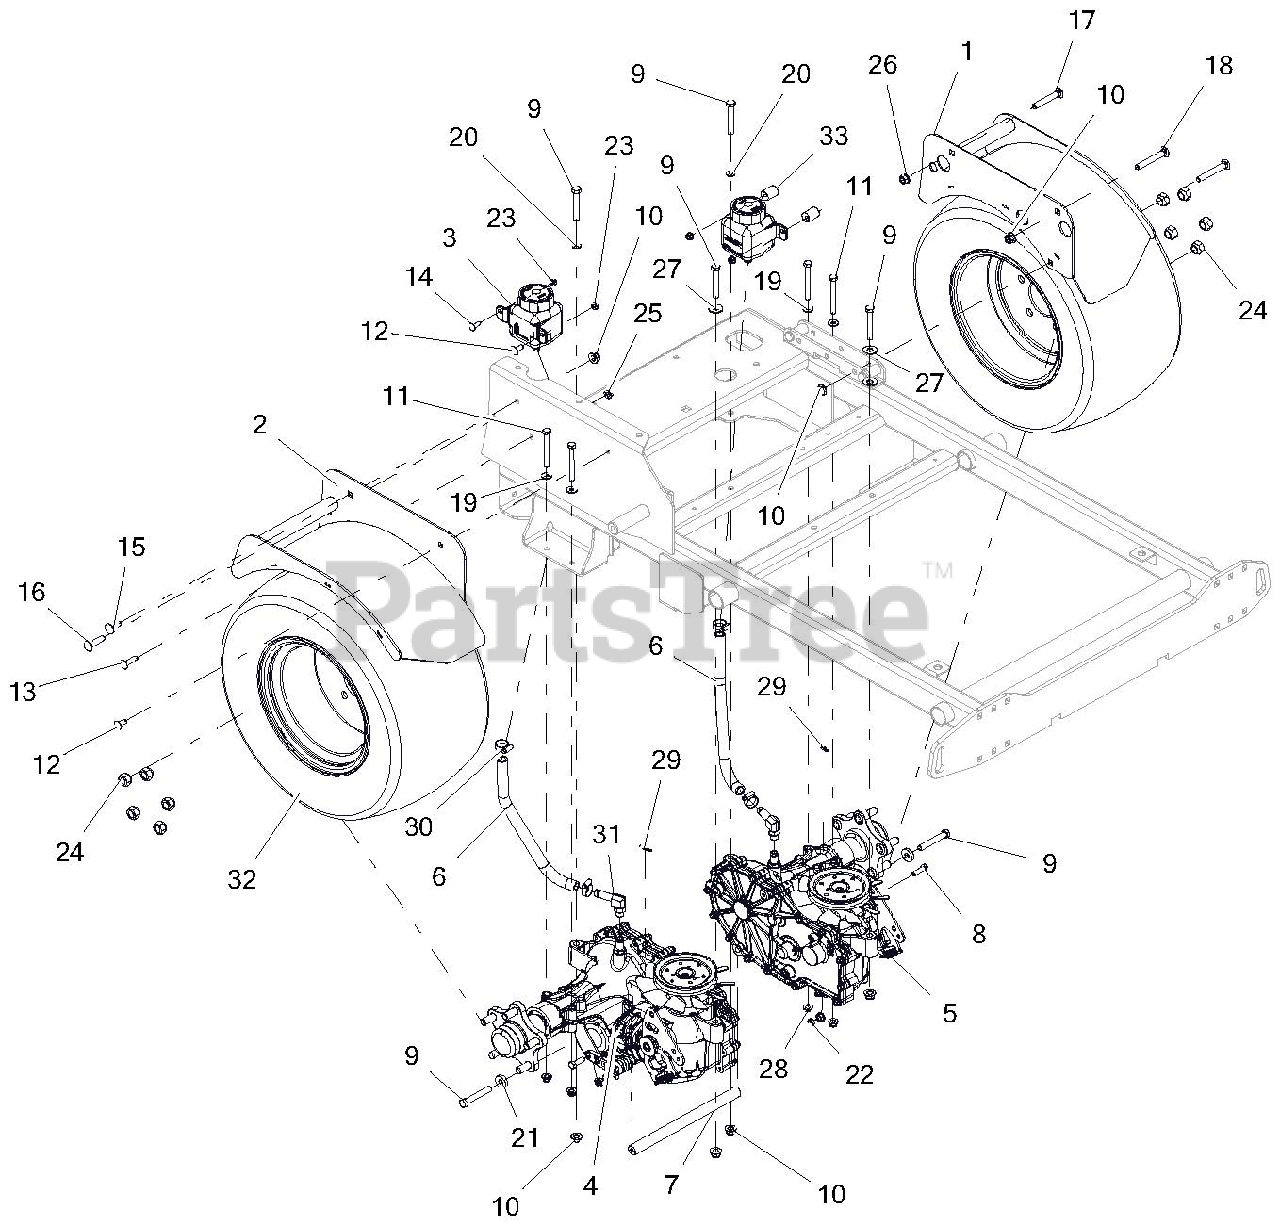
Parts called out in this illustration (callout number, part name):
1	WLDMT, LH FENDER
2	WLDMT, RH FENDER
3	TANK, EXPANSION ZT2800
4	TRANSAXLE, 3400, PRO-STANCE, RH
5	TRANSAXLE, 3400, PRO-STANCE, LH
6	HOSE, HYD OVERFLOW
7	SHAFT, CROSS BRACE
8	BLT-HEX .31-18X1.00 GR5 YWZC
9	BLT-HEX .38-16X2.50 GR5 YWZC
10	NUT-LK-NYL-FLG .38-16 YWZC
11	BLT-HEX .31-18X3.00 GR5 YWZC
12	BLT-RDHDSQNK .31-18X.75 G5 YWZC
13	BLT-RDHDSQNK .31-18X1.25 G5 Y
14	BLT-RDHDSQNK .25-20X.75 G5 YWZC
15	BLT-RDHDSQNK .38-16X1.00 G5 YWZC
16	BLT-RDHDSQNK .38-16X1.50 G5 Y
17	BLT-RDHDSQNK .38-16X2.50 G5 Y
18	BLT-RDHDSQNK .38-16X2.75 G5 Y
19	WSHR-FL-STL.312X.734X.065 YWZ
20	WSHR-FL-STL.281X.62X.065 YWZC
21	WSHR-FL-STL .406X1.00X.188 YWZC
22	@NUT-LK-CTR-JAM .31-18 YWZC
23	NUT-LK-NYL-FLG .25-20 YWZC
24	NUT, LUG .500-13
25	@NUT-SPNLK-FLG .312-18 YWZC
26	NUT, LK-TOP-FLG .38-16 YWZC
27	WSHR-FL-STL.438X1.00X.083 YWZC
28	NUT-LK-NYL-FLG .31-18 YWZC
29	PIN-HAIR, ENDRIES #25 YWZC
30	CLAMP, .88 DIA HOSE
31	FITTING, HYD
32	ASSM TIREWHEEL, 20X10.50X.8
33	ECCENTRIC
